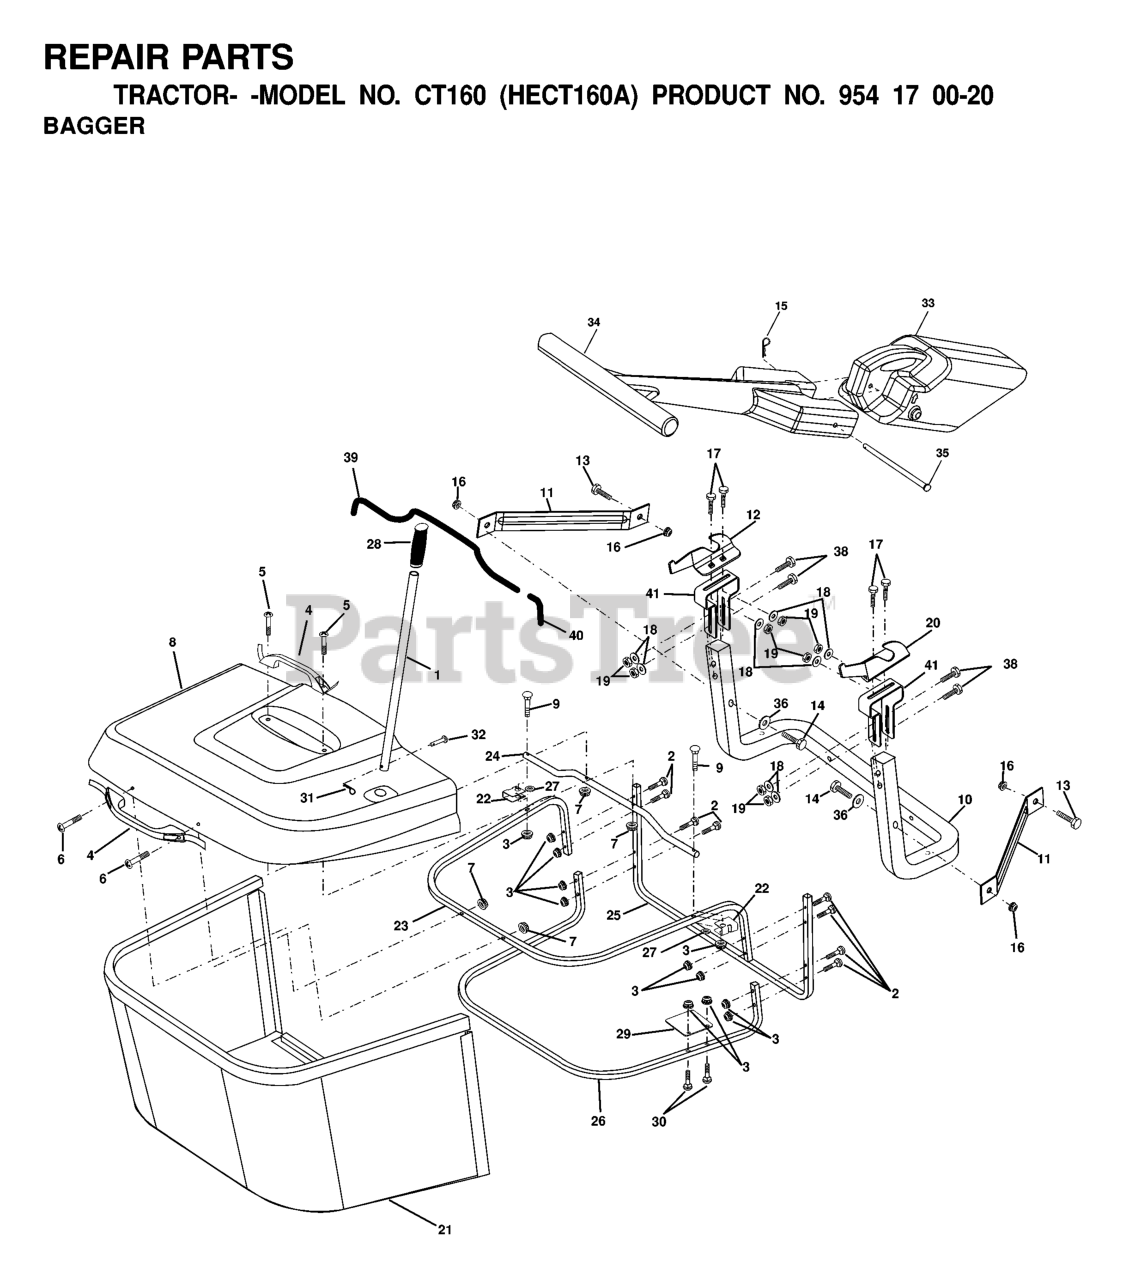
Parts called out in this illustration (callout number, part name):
1	TUBE HANDLE
2	Bolt Carriage 1/4-20 x 2.0 Gr.5
3	NUT T
4	HANDLE.BAGGER.W/LVRS.BLK.CRD
5	SCREW.PAN.HEAD
6	REPL BY 532 75 00-29
8	COVER
9	Bolt Carriage 1/4-20 x 2.25d x Gr.5
10	TUBE
11	BRACKET.SUPPORT.UPPER.BAG.CRD
13	BOLT
14	Bolt Hex 3/8-16 x 2-1/2 Gr. 5
15	RETAINER-SPRNG RB
16	NUT LOCK FLG 3/8-16 UNC
17	RP BOLT 5/16-18 X3/4 ZN/YEL GR
18	WASHER M
19	NUT.71038.31-18.HEX.NYLOCK
20	BRACKET
21	BAG
22	BRKT.SIDE.BAG.CRD
23	TUBE.UPPER.BAG.CRD
24	TUBE.PIVOT.BAG.CRD.BLACK
26	TUBE.LOWER.BAG.CRD
28	GRIP.HANDLE.BLACK
30	Bolt Carriage 1/4-20 x 1 Gr.5
31	RETAINER M
32	RIVET,DRILLED
33	MULCH PLUG, CTH150
34	HANDLE.MULCHER.92.CRD (2 2)
36	WASHER
38	BOLT.5/16-18X2.5
39	TRIM
40	TRIM
41	BRKT.VERT.ADJ.BAGGER.CRD
